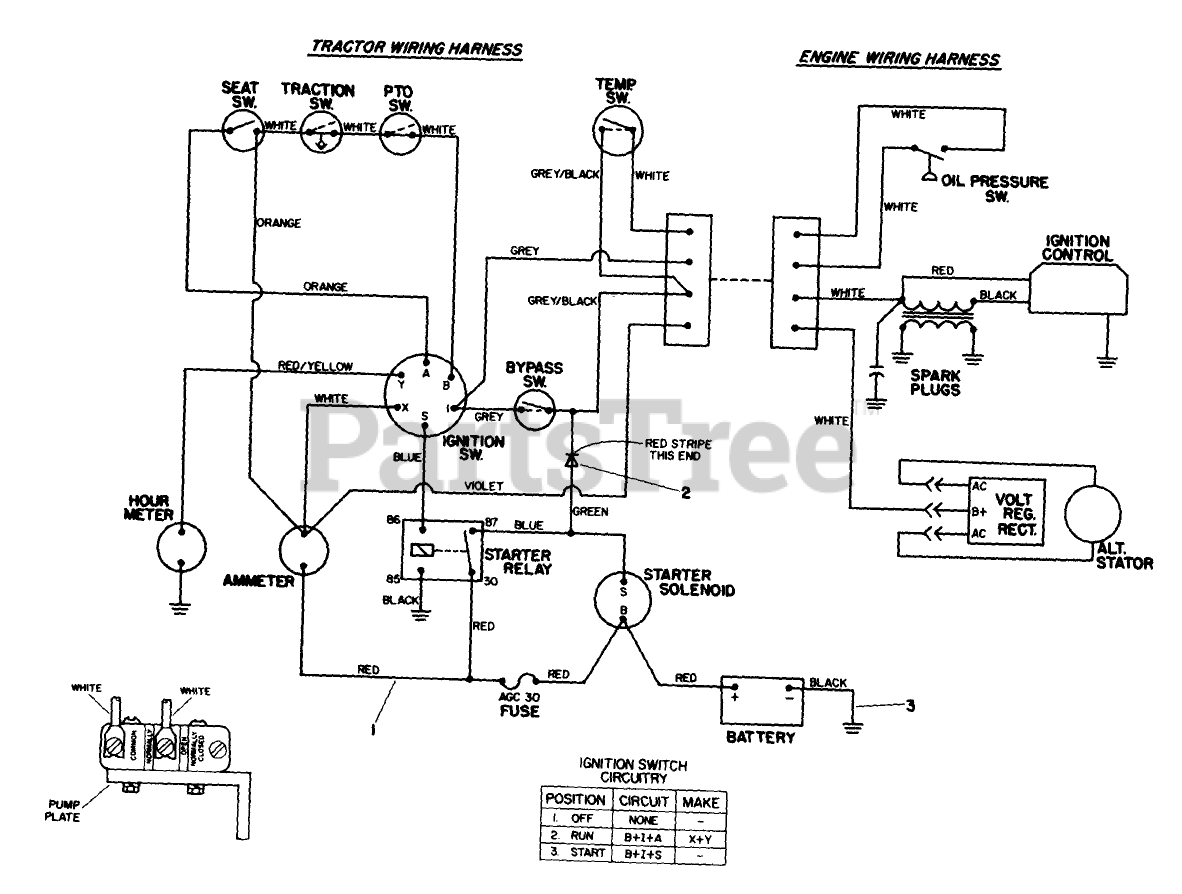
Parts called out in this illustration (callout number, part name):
1	Harness-Wire (Incl. Ref. #2)
2	DIODE
3	BATTERY GROUND WIRE
